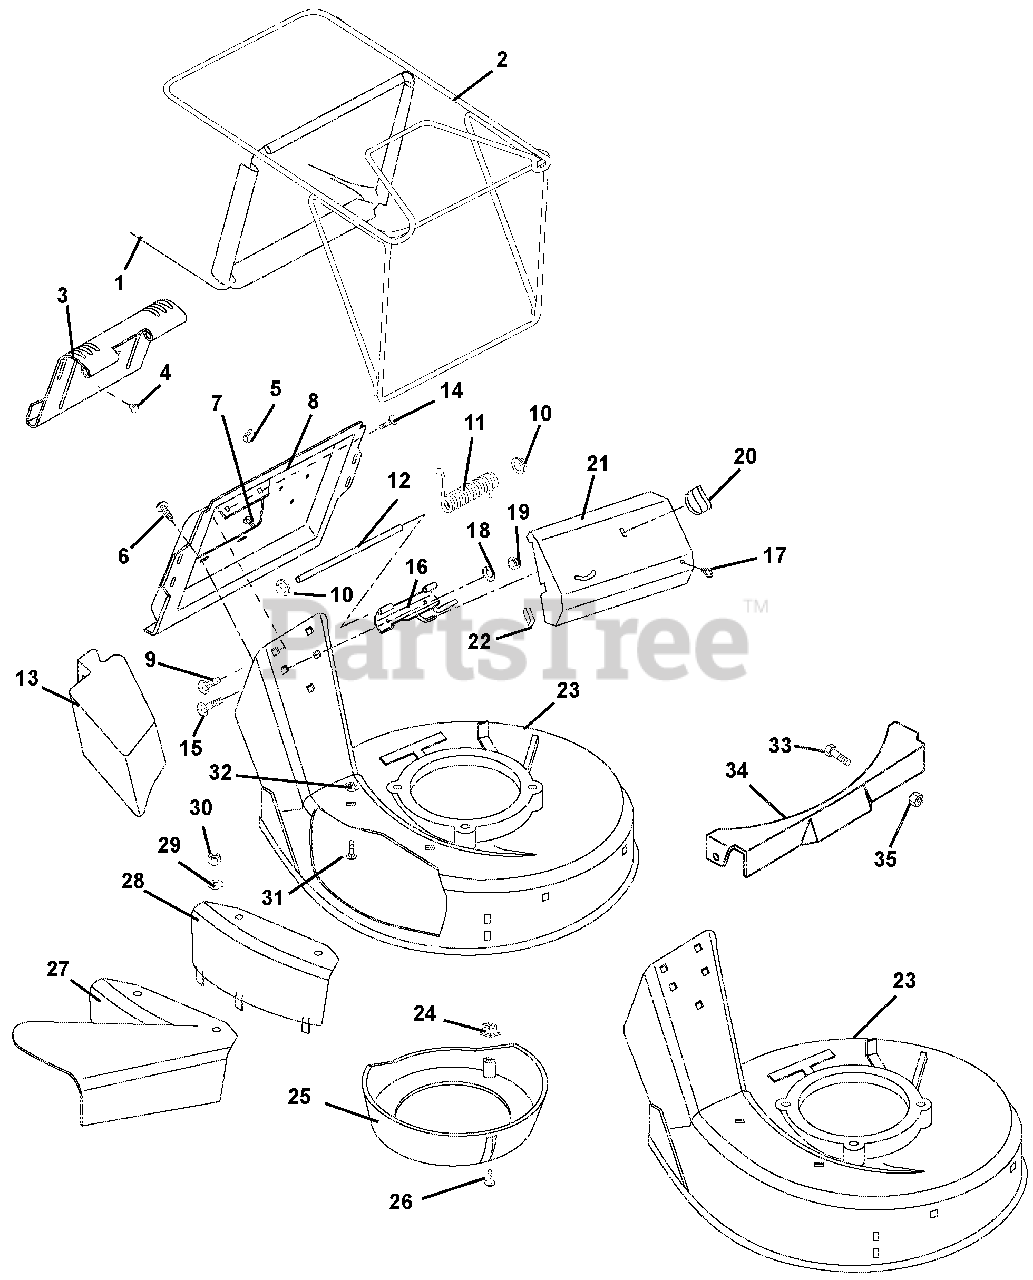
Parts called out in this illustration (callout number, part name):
1	BAG, CONSUMER BLACK 15 OZ/YD2
2	FRAME, BAGGER
3	CATCHER PLATE DOOR
4	BUTTON BUMPER
6	@SCR-TAP 12-24X.50 HWH TR YWZC
7	SCR-TAP 10-24X.375 TORX PHD YZ
8	CATCHER PLATE
8	PLATE, CATCHER
9	@BLT-RHDSSQNK .25-20X.38 G2YZ
10	PUSH NUT, .25
11	SG-TORS .120X.68X3.09
12	DOOR PIN
13	MULCH MASTER MULCHER ACCESSORY
14	@NUT-SPNLK-FLG .25-20 YWZC
15	@BLT-RDHDSQNK .25-20X.75 G5YZ
16	HINGE BASE WELDMENT
16	HINGE PLATE WELDMENT
17	SNAP-IN CLIP
18	WSHR-LK .250X.077 HVY YWZC
19	@NUT-HEX .25-20 YWZC
20	WING - NUT
21	COVER, DRIVE
22	TRIM BUMPER
23	MOWER PAN HEAD W/SFTYDECALS SP
23	MOWER PAN W/DECALS SP/COM
24	PLASTIC GROMMET
25	CENTER BAFFLE
26	SCR-TAP 10-16X.62 SLPH AB YWZC
27	SIDE DISCHARGE ASSEMBLY
28	COVER, SIDE DISCHARGE
29	@WSHR-FL-STL.406X.812X.065 YWZ
30	@NUT-LK-NYL .312-18 YWZC
31	BLT-RDHDSQSHK.31-18X.75 GR2 YW
32	NUT-PUSH .312
33	@BLT-RDHDSQNK .31-18X.50 G5YZ
34	PANEL-FRONT
35	@NUT-LK-CTR .31-18 YWZC
35	@NUT-SPNLK-FLG .312-18 YWZC
